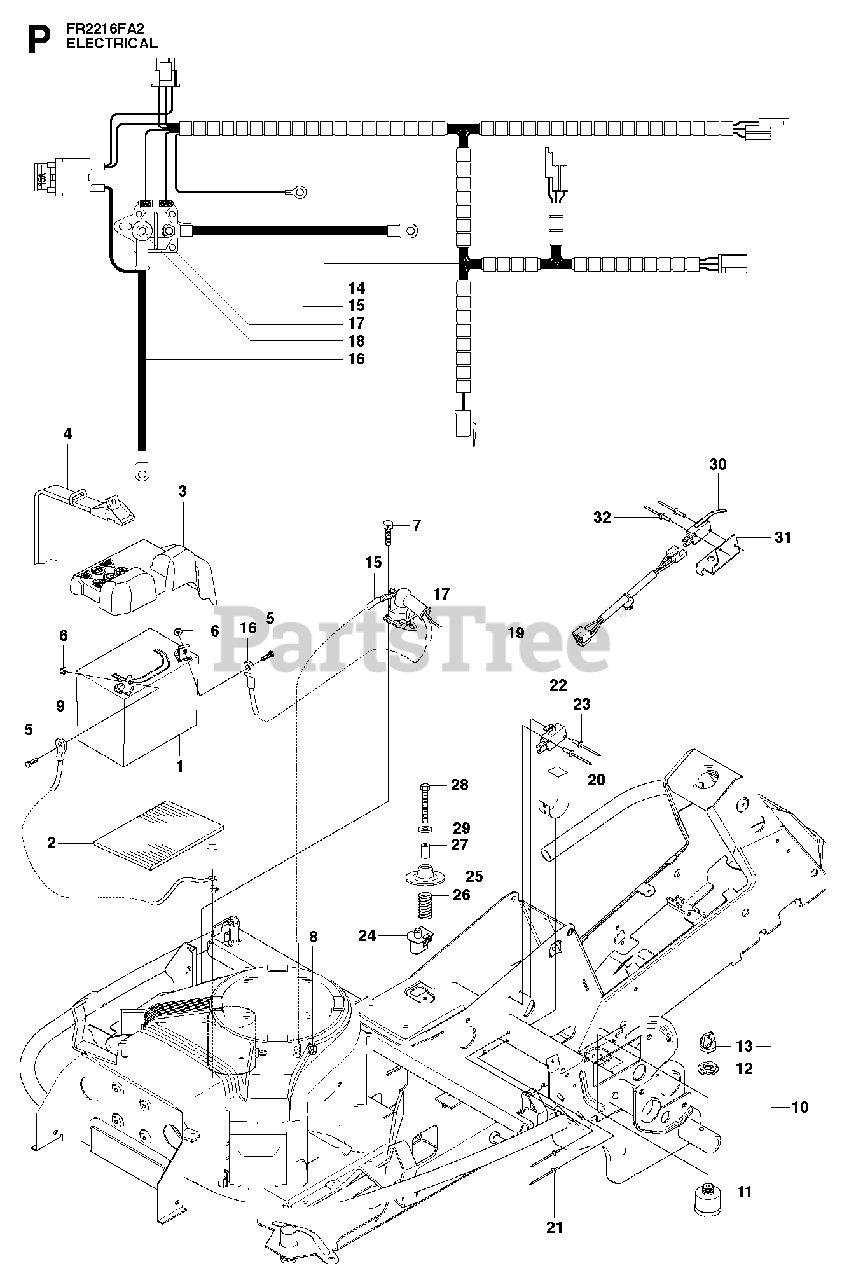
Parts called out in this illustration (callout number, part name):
5	SCREW EHHM
10	IGNITION SWITCH
11	IGNITION SWITCH
12	NUT
13	IGNITION KEY
19	WIRING
27	SPACER TUBE
28	SCREW
29	WASHER BRB 8.4X17
30	MICRO SWITCH
